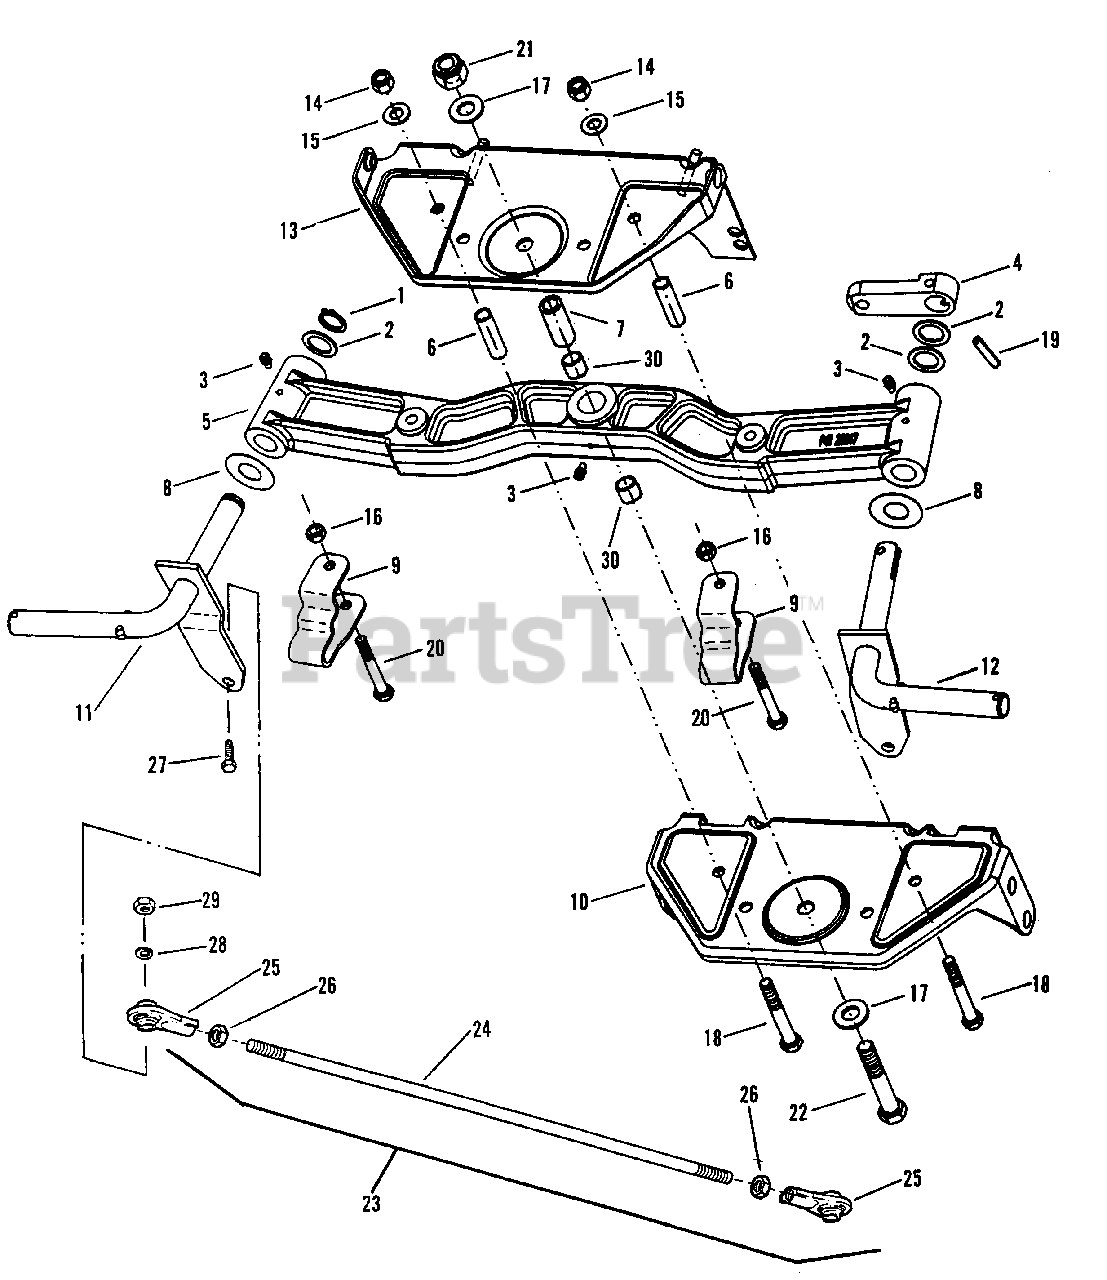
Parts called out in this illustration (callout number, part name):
1	RING, External Retaining 5/8
2	WASHER, 49/64 x 1-1/8 x 1/16 Flat
3	FITTING, 3/16 Lube
4	ARM, Steering
5	AXLE, Cast
6	SPACER, 25/64 x 1/2 x 1-13/16
7	SPACER, Center
8	WASHER, Thrust
9	BRACKET, Deck Hanger
10	BRACKET, Cast Axle - Rear
11	WELDMENT, Right Hand Spindle Wheel - Short
12	WELDMENT, Left Hand Spindle Wheel - Short
13	ASSEMBLY, Cast Axle Front Brkt.
14	NUT, 3/8 Nylon Lock
15	WASHER, 3/8 x 5/64 Flat
16	NUT, 5/16 - 18 Hex Center Lock
17	WASHER, 1/2 x 3/32 Flat
18	SCREW, 3/8-16 x 2-3/4" Hex Head Cap, Grade 2
19	PIN, 1/4 x 1-1/4 Roll
20	SCREW, 5/16-18 x 2-1/2 Hex Head Cap Grade 5
21	NUT, 1/2 Nylon Lock
22	SCREW, 1/2-13 x 3 Hex Head Cap Grade 5
23	ASSEMBLY, Tie Rod
24	ROD, Steering Connector
25	BALL JOINT, 3/8-24
26	NUT, 3/8-24 Hex Jam
27	SCREW, 3/8-16 x 1-1/2 Hex Head Cap, Grade 5
28	WASHER, 3/8 Split Lock
29	NUT, 3/8-16 Hex, Grade 5
30	BEARING, Sleeve
